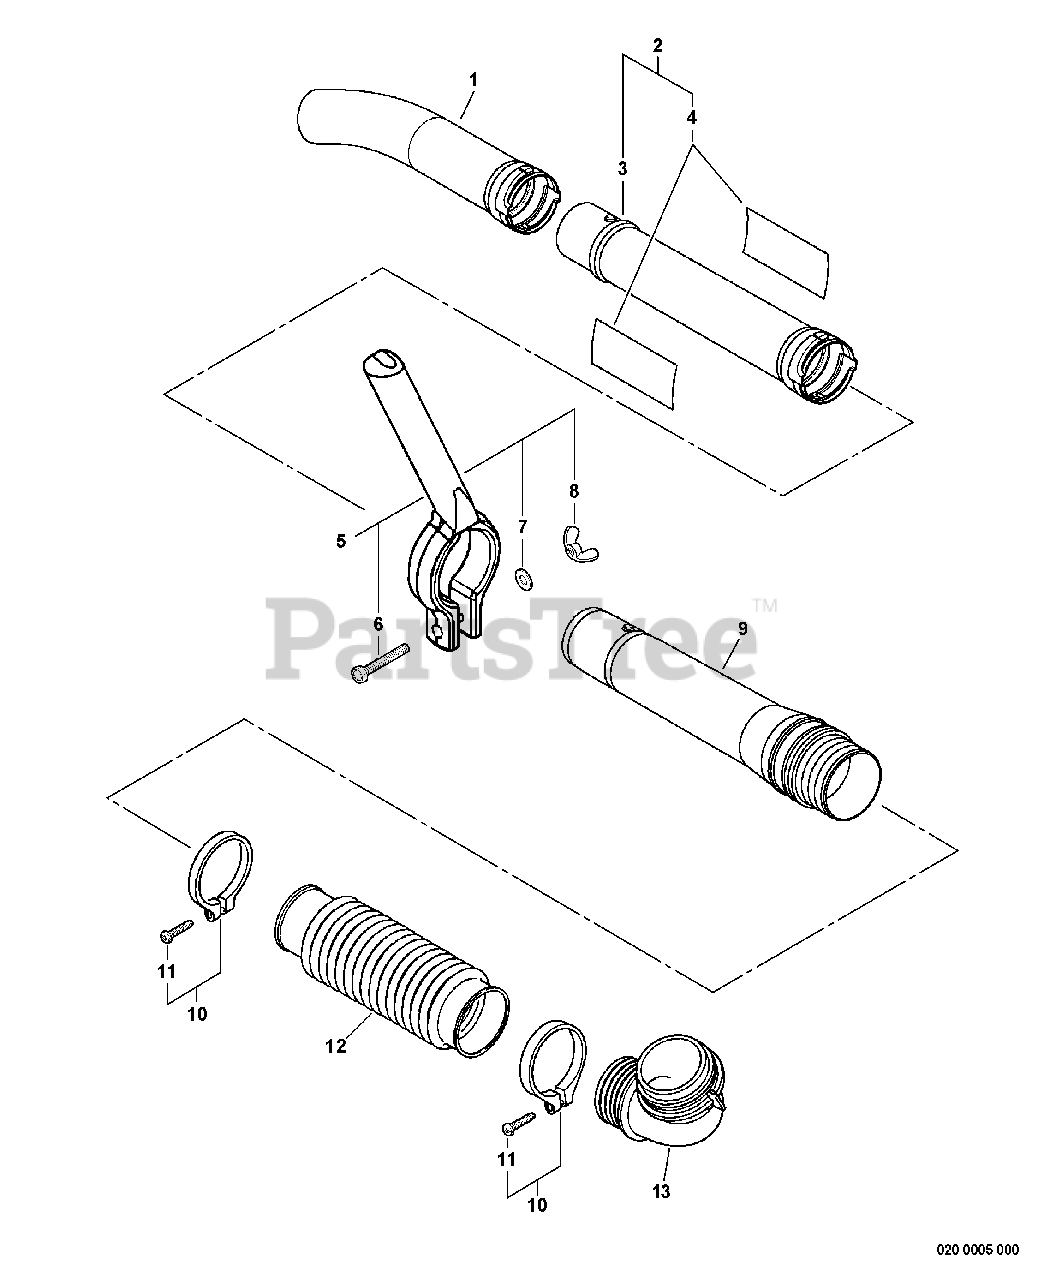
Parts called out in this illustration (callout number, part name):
1	TUBE, BLOWER - CURVED
2	BLOWER TUBE KIT - STRAIGHT
3	TUBE, BLOWER - STRAIGHT
4	LABEL - ECHO
5	HANDLE ASSY
6	BOLT - 6X45
7	WASHER - 6
8	WINGNUT - 6
9	TUBE, BLOWER - SWIVEL
10	CLAMP, HOSE
11	SCREW - 5X25
12	TUBE, BLOWER - FLEXIBLE
13	TUBE, BLOWER - ELBOW
